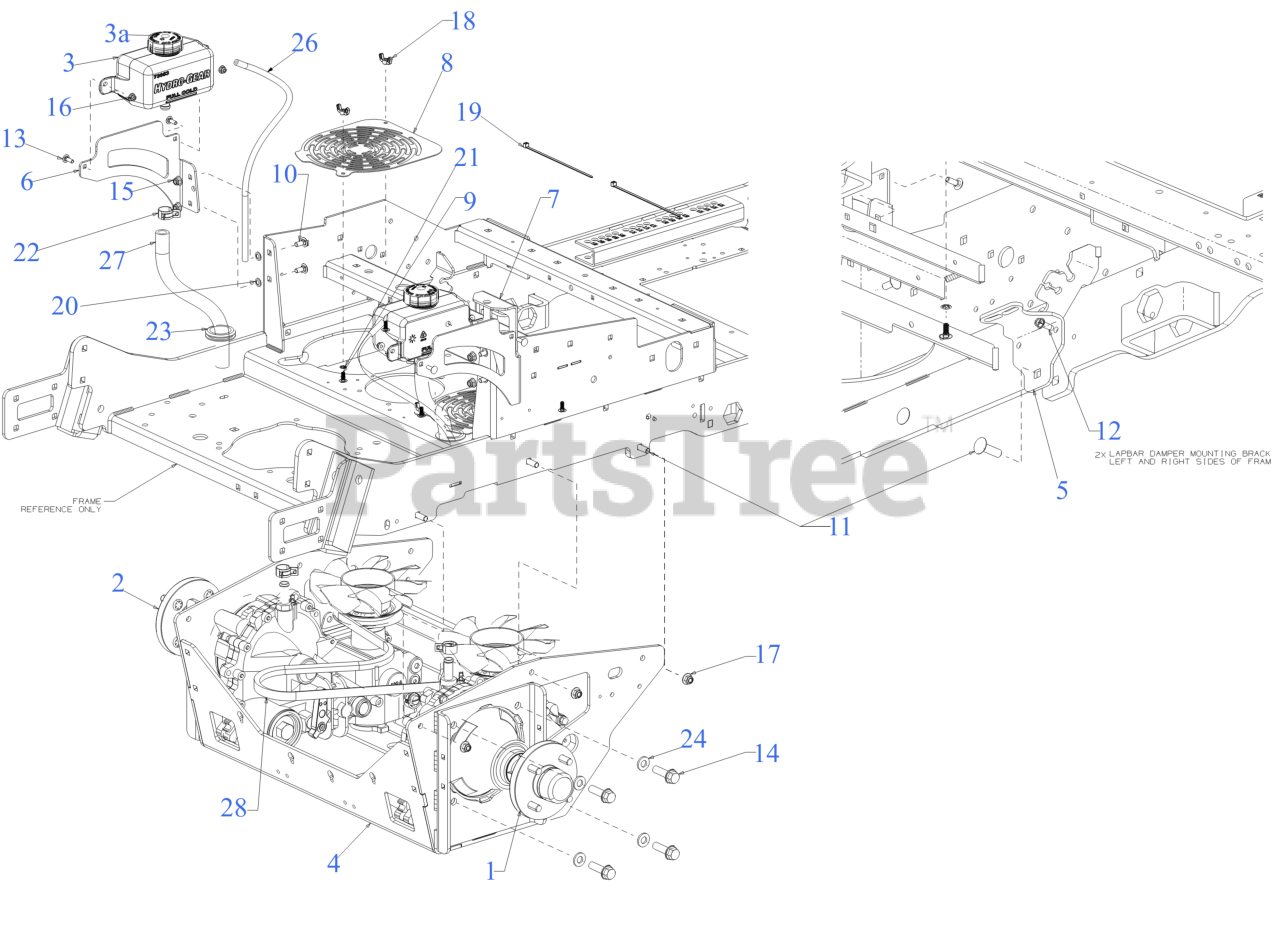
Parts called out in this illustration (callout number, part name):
1	HYDRO TRANSMISSION (RH)
2	HYDRO TRANSMISSION (LH)
3	1L EXPANSION TANK
4	SUB FRAME BRACKET
5	LAPBAR DAMPER MOUNT BRACKET
6	TANK MOUNT BRACKET (LH)
7	TANK MOUNT BRAKET (RH)
8	TRANSMISSION COVER PLATE
9	CARRIAGE BOLT 1/4-20 x .62
10	CARRIAGE BOLT 5/16-18 x .75
11	CARRIAGE BOLT 3/8-16 X1.25 GR5
12	SCREW 1/4-20 x .750
13	SCREW 1/4-20 x .75 GR5
14	FLANGE BOLT 1/2-13:1.75:GR5
15	FLANGE LOCK NUT 5/16-18
16	FLANGE LOCK NUT
18	WING NUT 1/4-20
19	7" CABLE TIE
21	RETAINER-BOLT .25ID x .50OD
22	HOSE CLAMP
23	RUBBER GROMMET (1.50X2.13X.563)
24	FLAT WASHER .510 x 1.000 x .125
26	VENT HOSE 3/16 ID 45"LG
27	OIL HOSE 5/8 ID X 12.5 LG
28	V-BELT 66.34"
